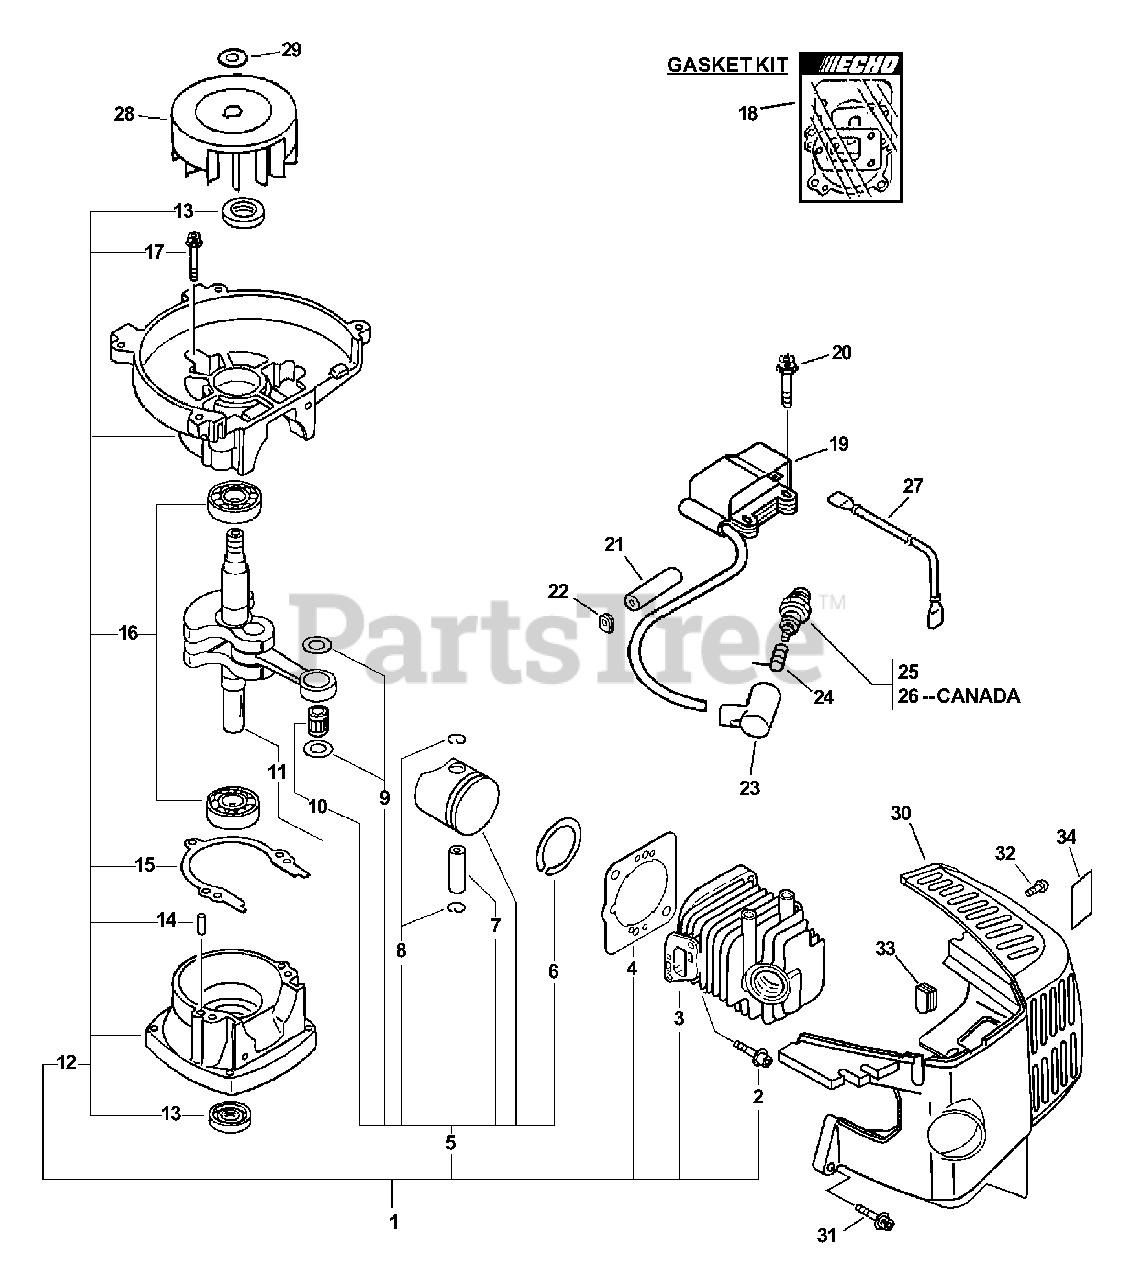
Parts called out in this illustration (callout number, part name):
1	SHORT BLOCK
2	SCREW 4×22
3	CYLINDER
4	GASKET, CYLINDER
5	PISTON KIT
6	RING, PISTON
7	PIN, PISTON 8
8	RING, SNAP
9	WASHER, THRUST
10	BEARING, NEEDLE
11	CRANKSHAFT ASSY
12	CRANKCASE KIT
13	SEAL, OIL 12
14	PIN, LOCATING 4
15	GASKET, CRANKCASE
16	BEARING, BALL - 6201 C3
17	BOLT 5×28
18	GASKET KIT
19	COIL, IGNITION
20	BOLT 4×20
21	TUBE, INSULATOR
23	CAP, SPARK PLUG
24	TERMINAL, SPARK PLUG
25	SPARK PLUG - BPM8Y
26	SPARK PLUG - BPMR8Y
27	LEAD - IGNITION
28	FLYWHEEL
29	WASHER 8.5×16×1.2
30	COVER, ENGINE
31	BOLT 5×22
32	BOLT 4×8
33	PLUG
34	LABEL, CAUTION - HOT
